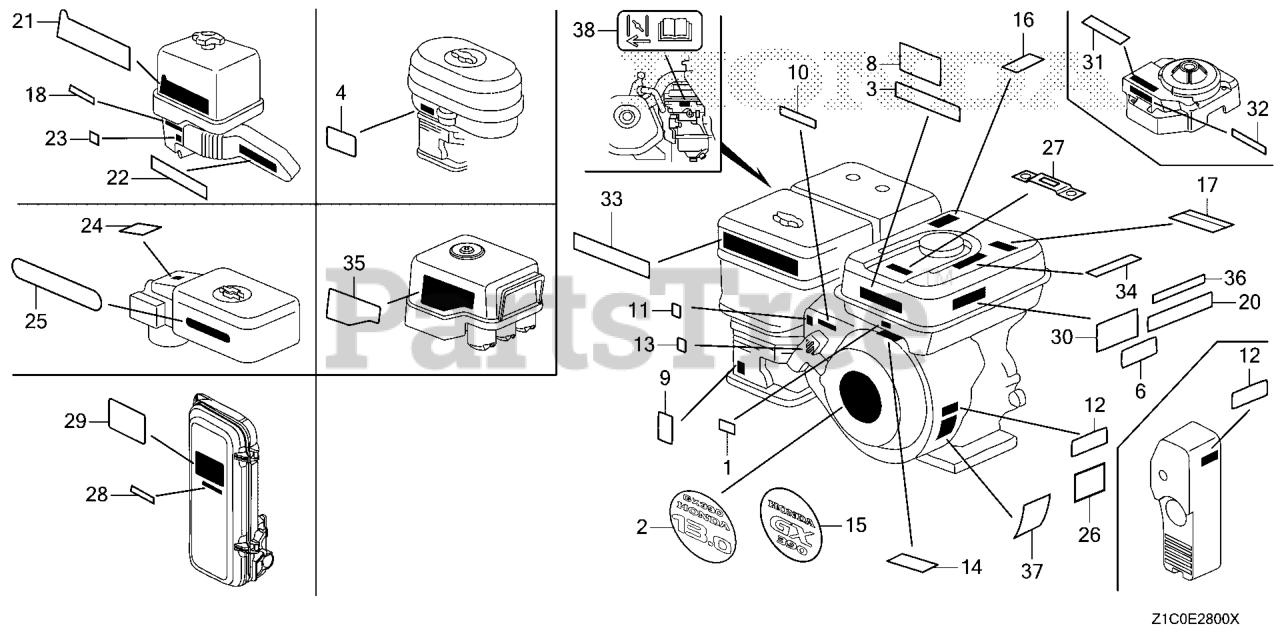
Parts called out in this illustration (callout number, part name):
9	MARK, CHOKE
10	MARK, THROTTLE INDICATION
15	EMBLEM (GX39 (HONDA)
35	MARK, SALES POINT
